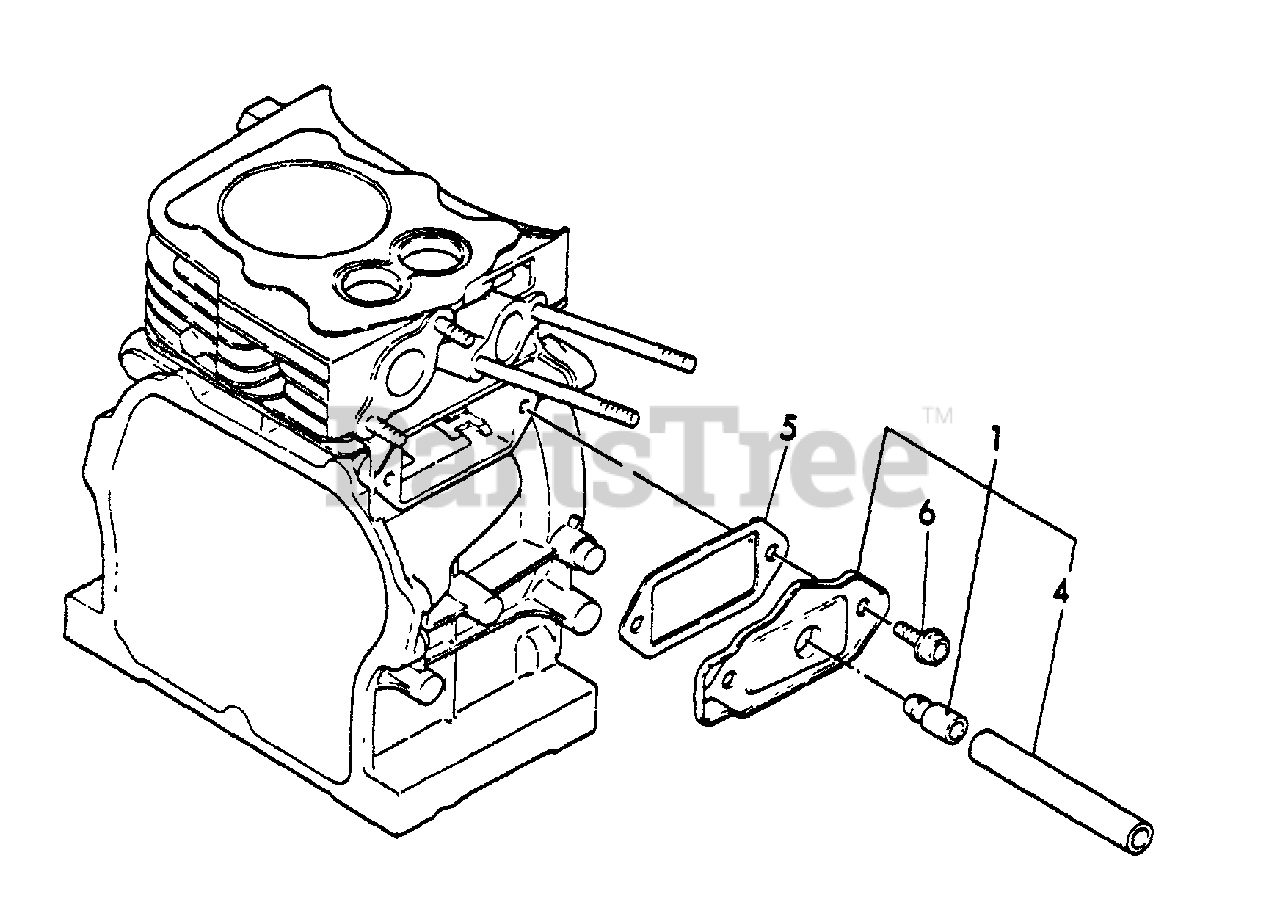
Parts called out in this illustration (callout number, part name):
1	BREATHER ASSY
4	PIPE, BREATHER
5	GASKET
6	BOLT - 6×8 -- PLATED
